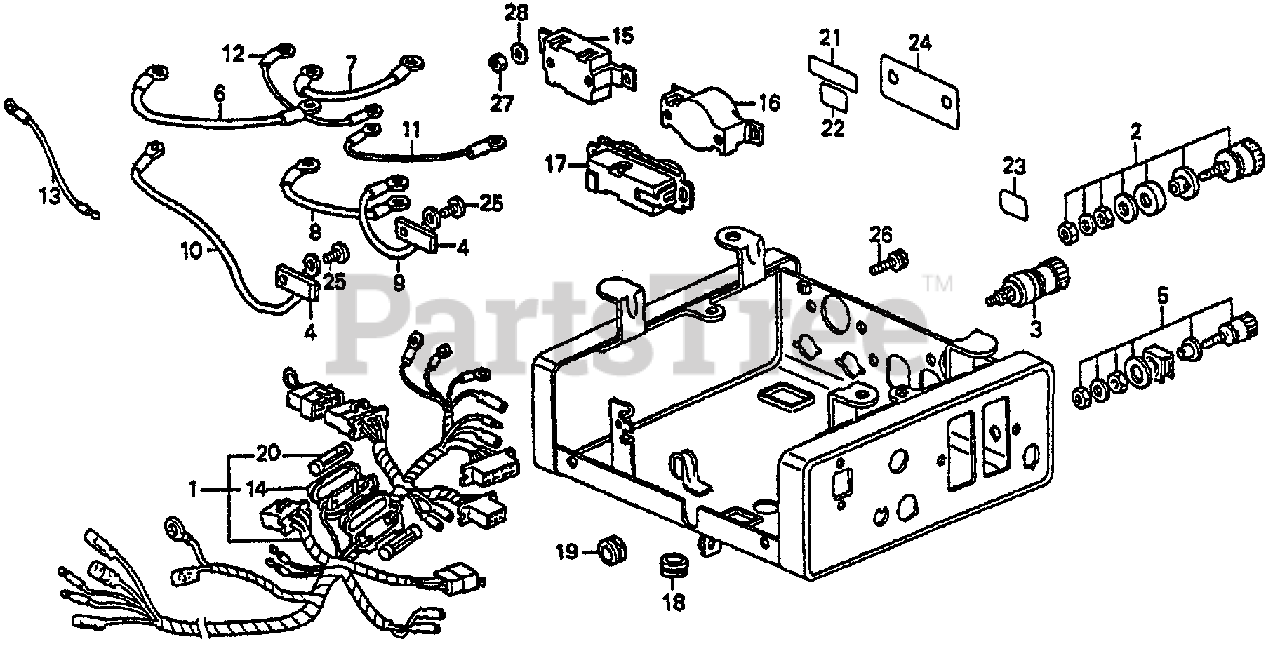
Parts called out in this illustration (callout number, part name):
1	WIRE HARNESS, BOX
2	TERMINAL, D.C. OUT (+)
3	TERMINAL, D.C. OUT (-)
4	TERMINAL, BREAKER
5	TERMINAL ASSY., GROUND
6	WIRE, RECEPTACLE CONNECTING (200)
7	WIRE, RECEPTACLE CONNECTING (100)
8	WIRE, RECEPTACLE CONNECTING (100) (NOT AVAILABLE)
9	WIRE, RECEPTACLE CIRCUIT BREAKER CONNECTING (100)
10	WIRE, RECEPTACLE CIRCUIT BREAKER CONNECTING (200)
11	WIRE, RECEPTACLE CONNECTING (100) (GROUND) (NOT AVAILABLE)
12	WIRE, RECEPTACLE CONNECTING (200) (GROUND)
13	WIRE, D.C. OUT
14	CASE, FUSE CONNECTOR
15	RECEPTACLE (20A/250V)
16	RECEPTACLE (30A 250V)
17	RECEPTACLE (15A-125V)
18	GROMMET B, TUBE
19	GROMMET, WIRE HARNESS
20	FUSE (5A)
21	MARK, CAUTION
22	MARK, OUTPUT
23	MARK, GROUND
24	MARK B, D.C. OUTPUT
25	SCREW, PAN (5X8)
26	SCREW-WASHER (4X12)
27	NUT, HEX. (4MM)
28	WASHER, PLAIN (4MM)
